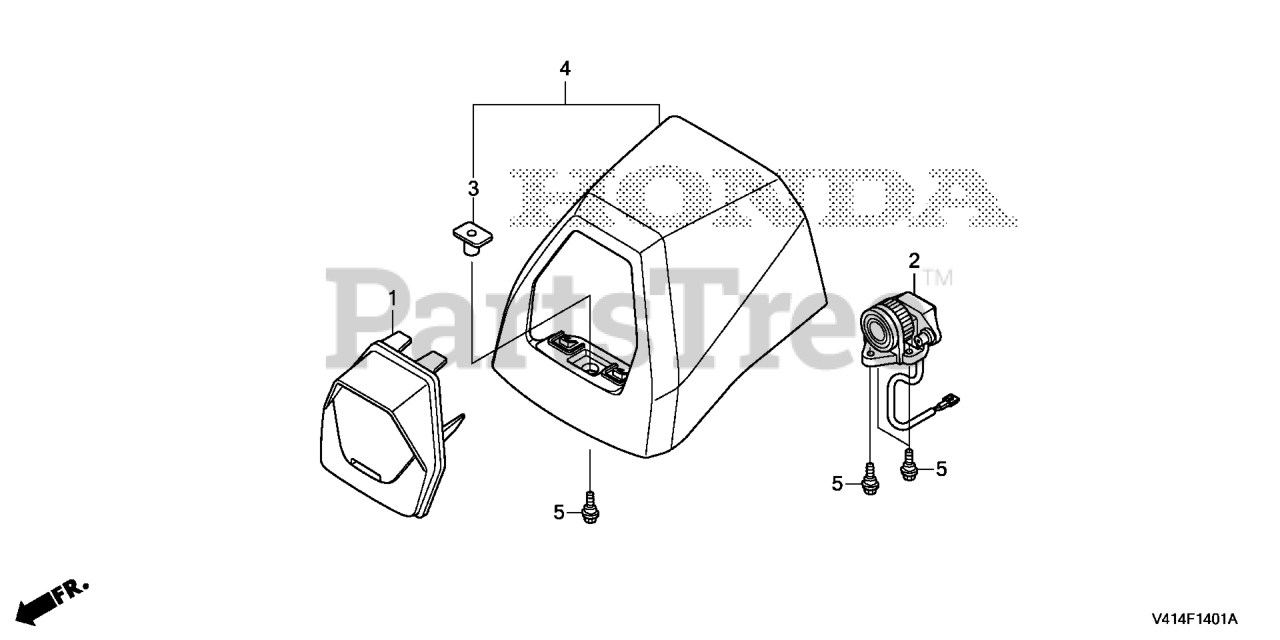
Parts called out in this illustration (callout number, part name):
1	LENS, HEADLIGHT *TCLEAR* (CLEAR)
2	HEADLIGHT ASSY.
3	NUT, SPECIAL (6X7)
4	COVER, HEADLIGHT *NH296* (ALPS GRAY)
5	BOLT, FLANGE (6MM)
